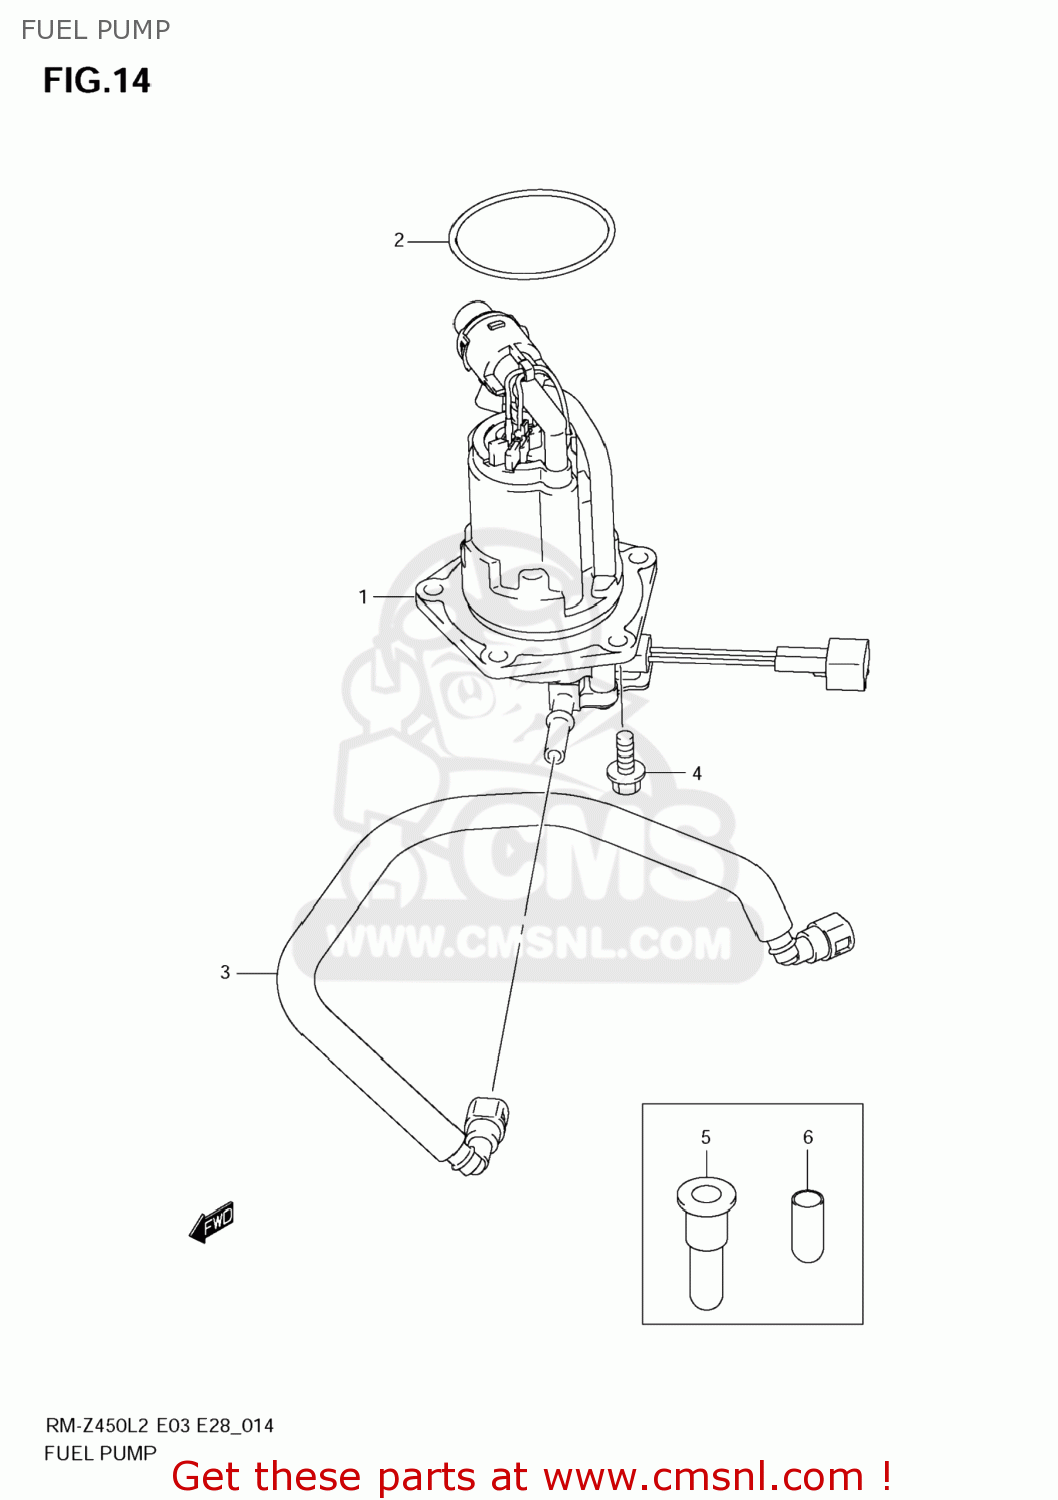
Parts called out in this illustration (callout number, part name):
1	PUMP ASSY,FUEL
2	O RING
3	HOSE,FUEL
4	BOLT
5	CAP,FUEL HOSE
6	CAP,FUEL PUMP
